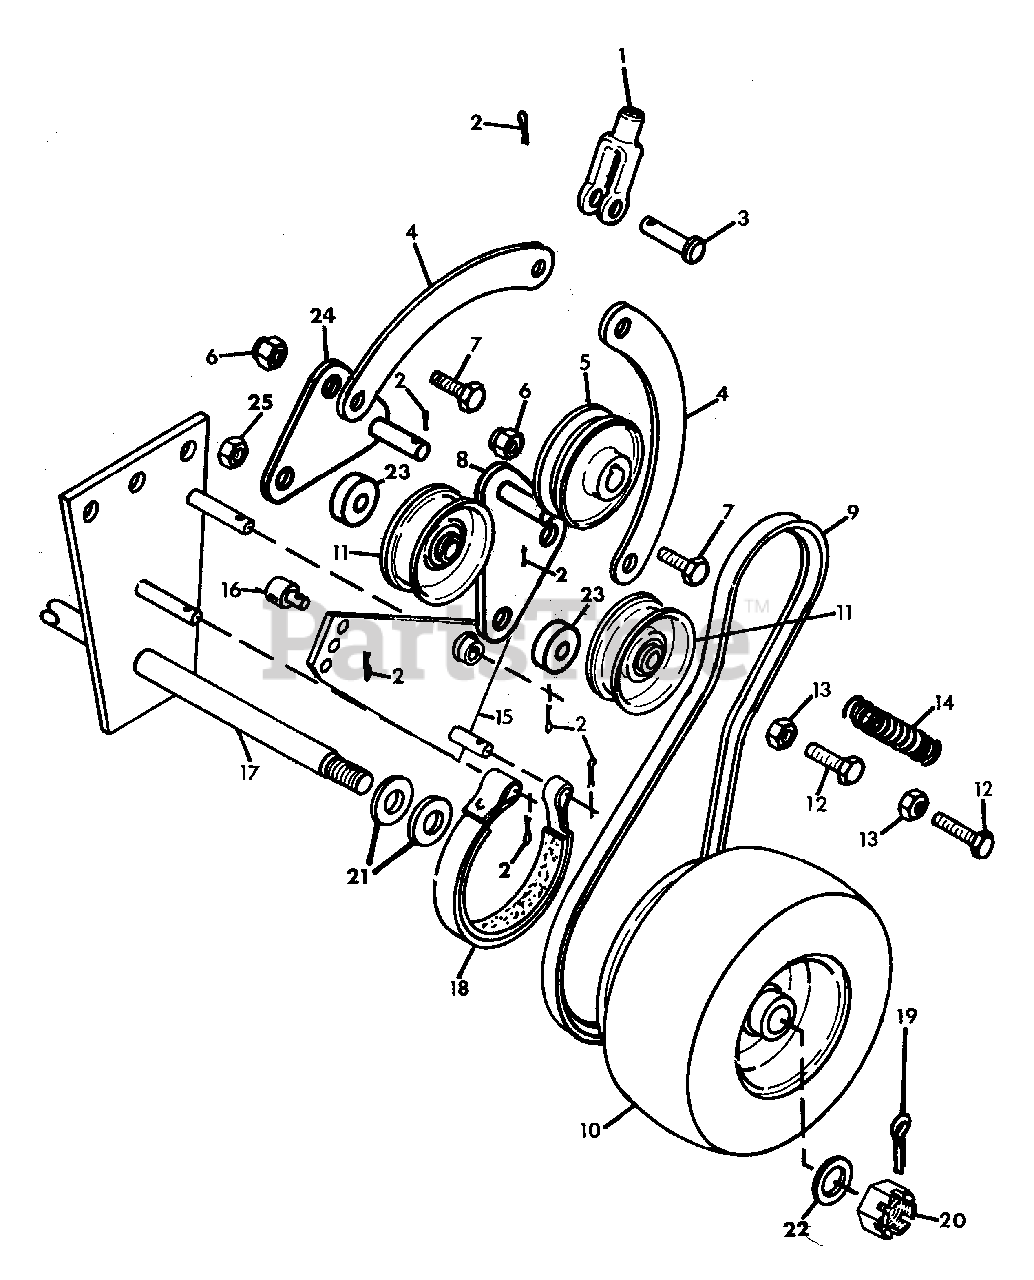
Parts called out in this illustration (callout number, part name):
1	Clevis, 5/16
2	Pin, Cotter .09x.625
3	Pin, Clevis .312x.812
4	Strap, Wheel Clutch Actuating
5	Pulley, Jack-Shaft
6	Nut, Lock 5/16-18
7	Bolt, Hex 5/16x.625
8	Lever, Wheel Clutch Idler
9	Belt, Traction
10	Assembly, Wheel & Tire
11	Sheave, Idler
12	Bolt, Hex 3/8-16x2.0
13	Nut, Hex 3/8-16
14	Spring
15	Weldment, Brake Lever L.H.
15	Weldment, Brake Lever R.H.
16	Pivot, Brake Rod
17	Weldment, Axle
18	Assembly, Brake Band L.H.
18	Assembly, Brake Band R.H.
19	Pin, Cotter .156x1.50
20	Nut, Slotted 3/4-16
21	Washer, Flat .938x1.750x.134
22	Washer, Flat .812xl.375x.100
23	Spacer, Idler
24	Weldment, Wheel Clutch L.H.
25	Nut, Lock 3/8-16
